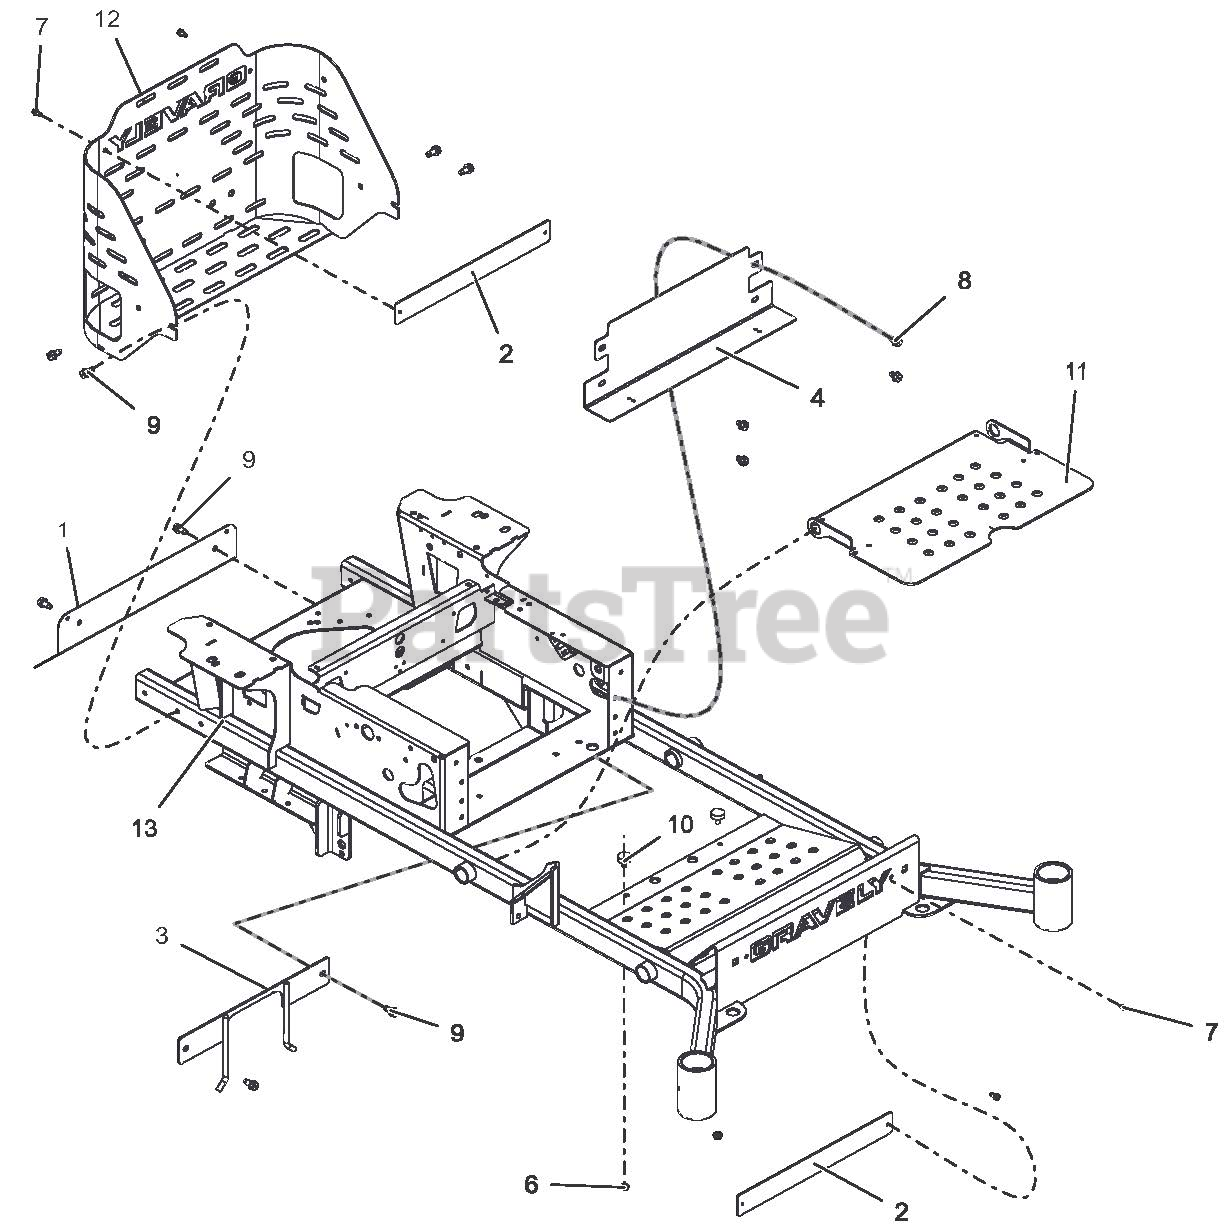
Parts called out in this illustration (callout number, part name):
1	SHIELD, MUFFLER HEAT
2	PLATE, BUMPER 2.00 X 16.50 - BLK
3	WLDMT, PTO BELT FINGER-BLACK
4	PLATE, PT/PT100 KICK-RED
6	@NUT-SPNLK-FLG .312-18 YWZC
7	SCR-TAP .25-20 X .50 HWH TR YWZ
8	SCR-TAP .38-16 X .50 HWH TR YWZ
9	SCR-TAP .38-16 X .75 HWH TR YWZ
10	BUMPER, RUBBER
11	FOOT, PLATE W/SAFETY DECALS
12	REAR BUMPER W/SAFETY DECALS
13	60" MAIN FRAME W/ SAFETY DECALS
